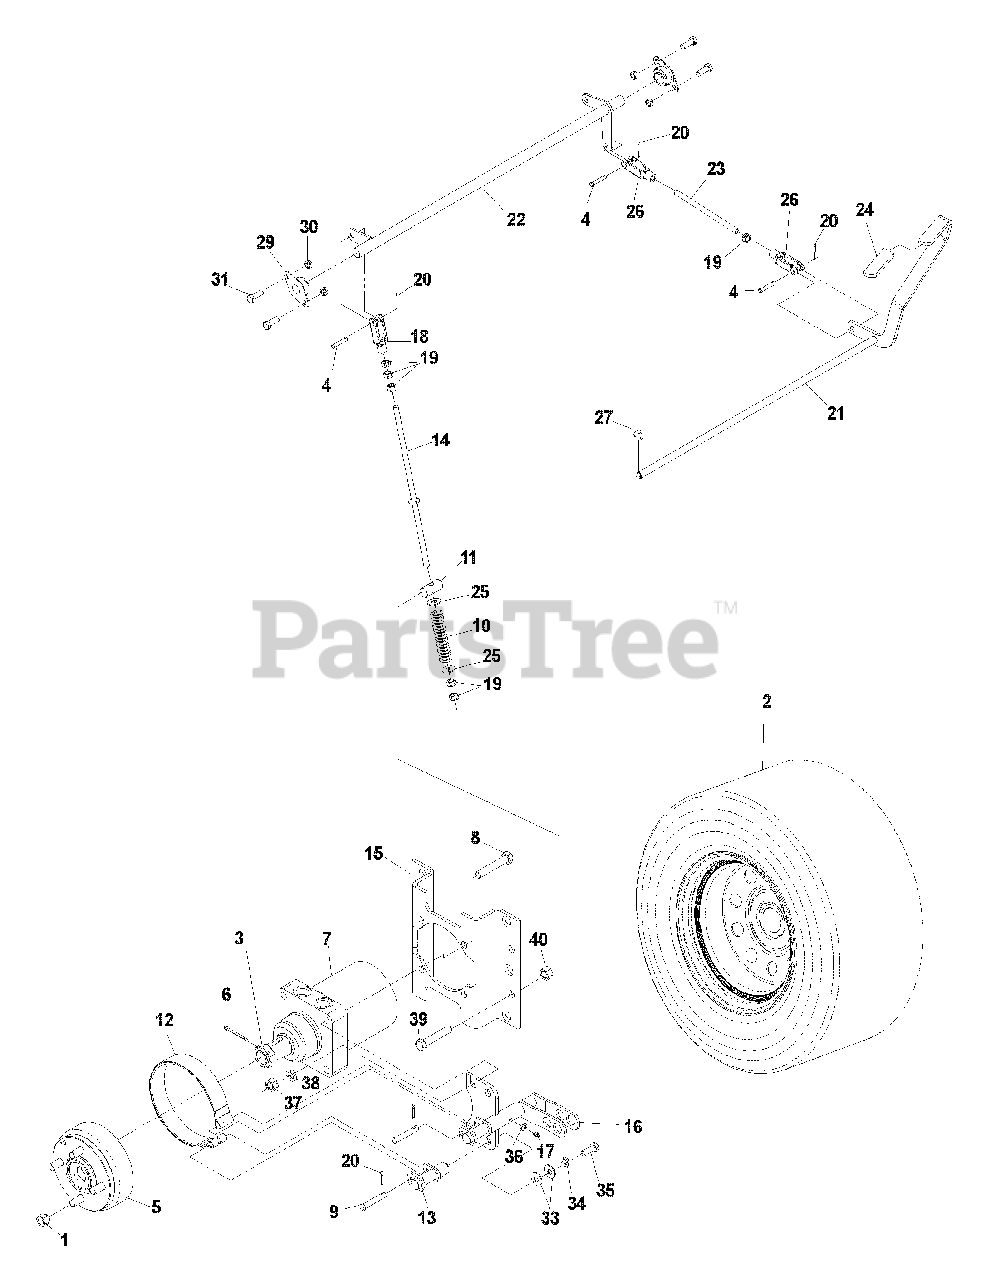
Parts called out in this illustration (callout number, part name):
1	LUG NUT 1/2F
2	REAR TIRE ASM.(COMPLETE)(42" DECK)
2	TIRE, 23 X 8.5-12
2	RIM, 12 X 7
2	VALVE STEM
2	REAR TIRE ASM.(COMPLETE)(48" & 52" DECK)
2	TIRE, 23 X 10.5-12
2	RIM, 12 X 8.5
3	HEX SLOTTED NUT
4	CLEVIS PIN, 3/8 X 1 1/8
5	HUB, W/BRAKE DRUM
6	KEY-COTTER 4 MM X 45 MM
7	WHEEL MOTOR
8	HCS 1/2C X 2 3/4
9	PIN-CLEVIS, 3/8 X 2
10	SPRING-BRAKE COMPRESSION
11	PIN-TRUNION
12	BAND-BRAKE
13	BRAKE BAND SUPPORT
15	MOTOR STANDOFF
16	BRAKE WLDMT
17	ZERK, STRAIGHT, 1/4-28
18	YOKE, 3/8-24
19	NUT, HEX, 3/8F
20	PIN-COTTER, 1/8 X 3/4
21	BRAKE LEVER WLDMT
22	BRAKE CROSS SHAFT
23	LINKAGE SHORT
25	WASHER, 7/16
27	E-RING, 1/2
29	FLANGE BEARING
30	NUT, 3/8C, NYLOC
31	HCS 3/8C X 1
32	COTTER PIN
33	WASHER 3/8, FLAT
34	LOCKWASHER, 3/8
35	HCS 3/8C X 1, GD 8
38	LOCKWASHER, 1/2
39	HCS 1/2 X 1 1/4, SERR WASHER
40	NUT, 1/2C, NYLOC
